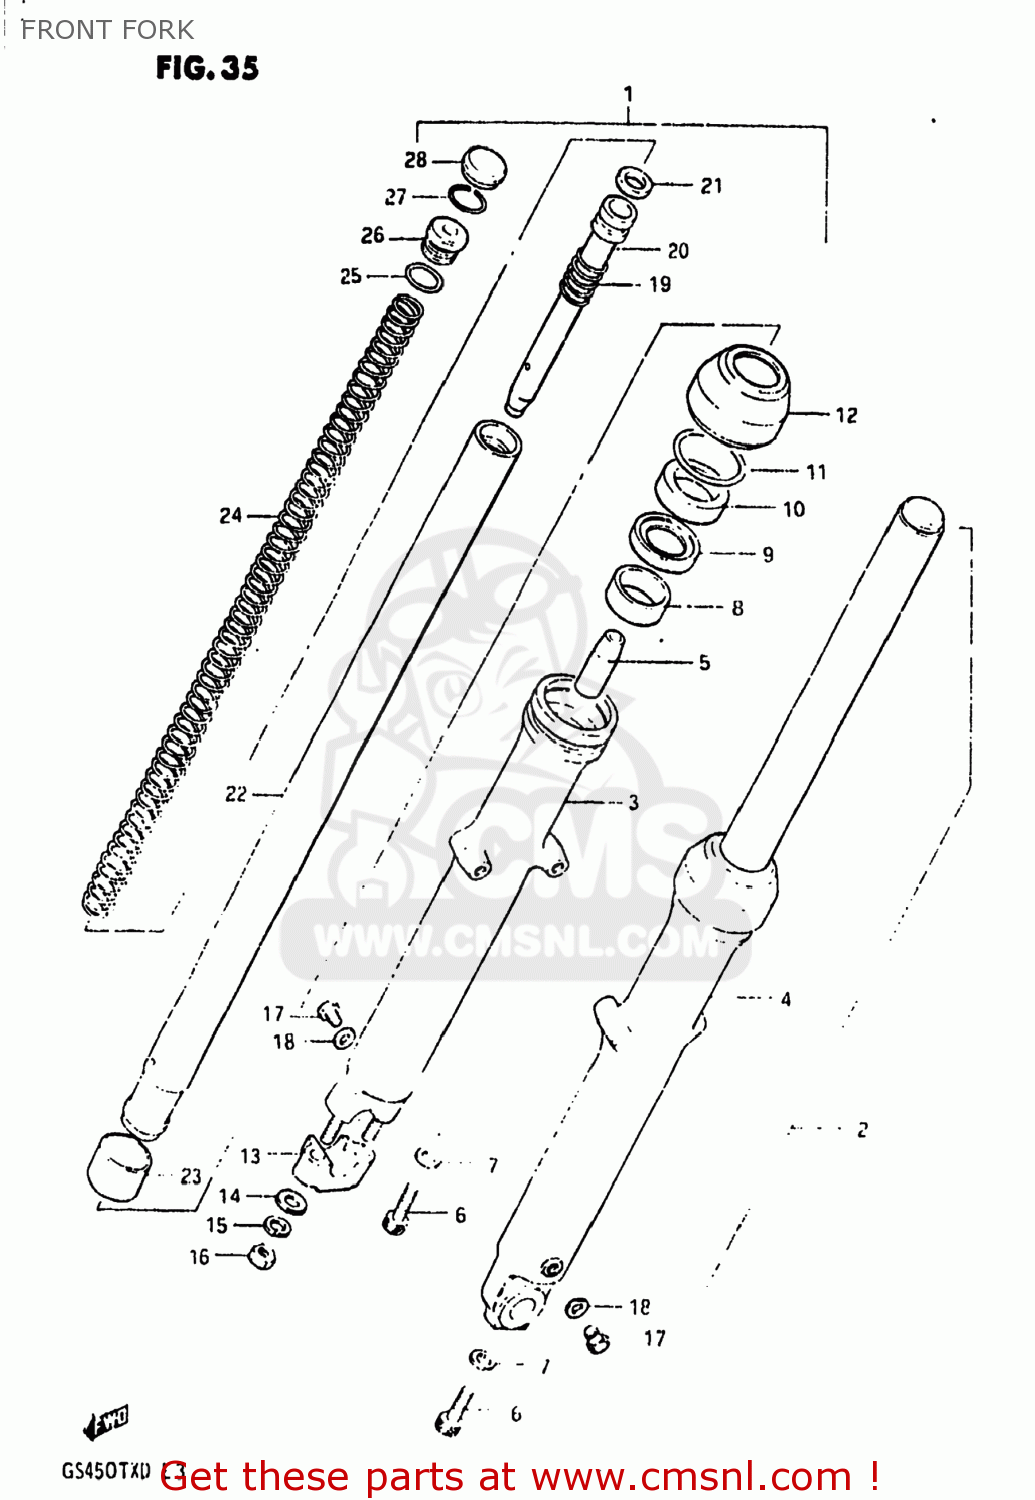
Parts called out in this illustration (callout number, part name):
1	DAMPER ASSEMBLY,RIGHT
2	DAMPER ASSEMBLY,LEFT
3	TUBE,FORK,OUTER,RIGHT
4	TUBE,FORK,LEFT,OUTER
5	PIECE,OIL LOCK
6	BOLT(8X27)
7	GASKET (NAS)
8	BUSH,GUIDE
9	SPACER,OIL SEAL
10	OIL SEAL,FRONT FORK
11	CIRCLIP,FORK OIL SEAL
12	DUST SEAL
13	HOLDER,AXLE
14	WASHER
15	LOCK WASHER
16	NUT (8MM)
17	BOLT
18	GASKET,DRAIN,PLUG (NAS)
19	SPRING,REBOUND
20	CYLINDER,FRONT FORK
21	RING,PISTON
22	TUBE,FORK,INNER
23	BUSH
24	SPRING
25	O RING
26	SEAT,SPRING
27	RING,STOPPER
28	CAP,FRONT FORK
